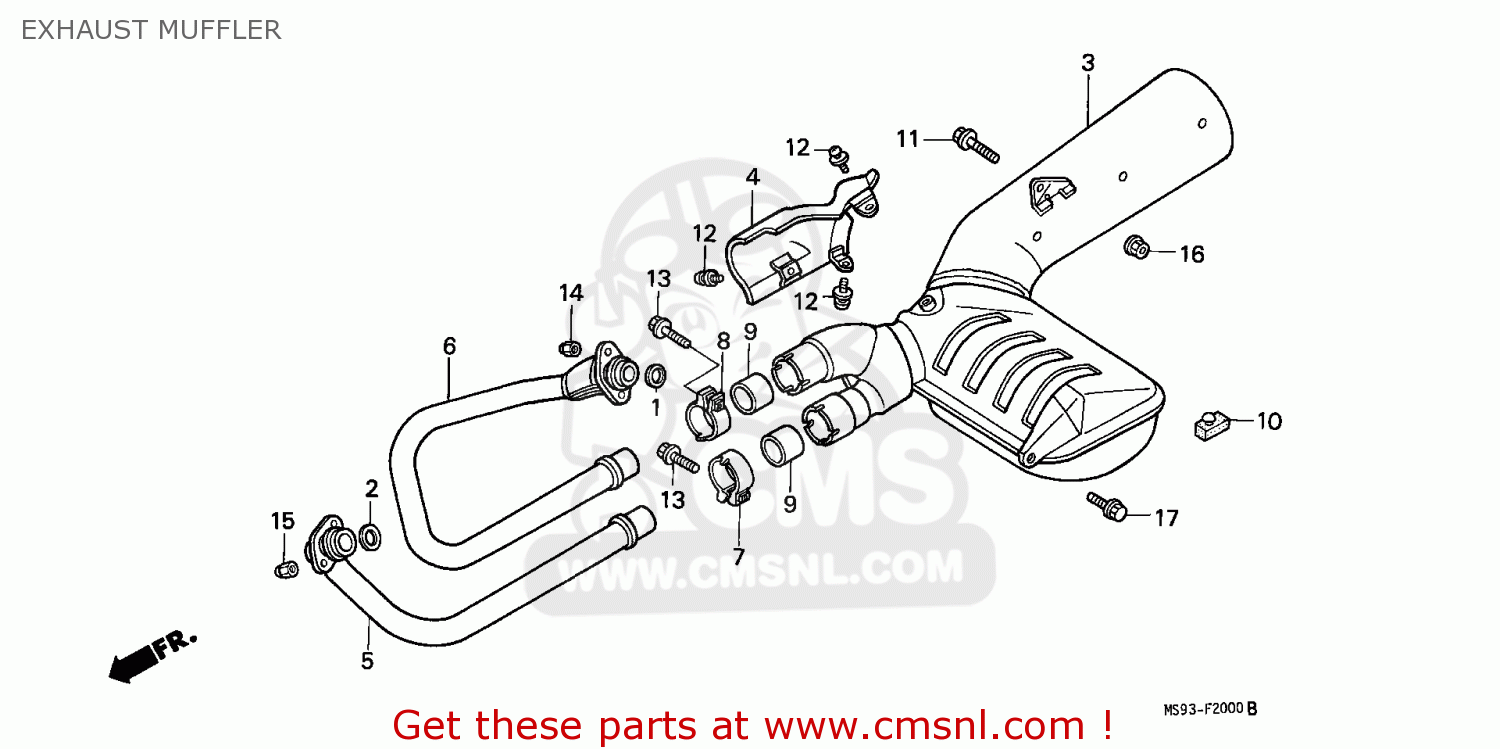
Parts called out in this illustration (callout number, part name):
1	GASKET,EX.PIPE (NAS)
2	GASKET,EX.PIPE (NAS)
3	CHAMBER COMP.,EX.
4	COVER,CHAMBER
5	PIPE,FR.EX.
6	PIPE,RR.EX.
7	BAND,R MUFFLER
8	BAND,L MUFFLER
9	PACKING,MUFFLER (NAS)
10	RUB,STAND STOPPER
11	BOLT,SPL,FLG,8X30
12	SCREW,WASH.6X10
13	BOLT,FLANGE,8X35
14	NUT,FLA.CAP 8MM
15	NUT,FLA.CAP 8MM
17	BOLT,SPECIAL SOCK
